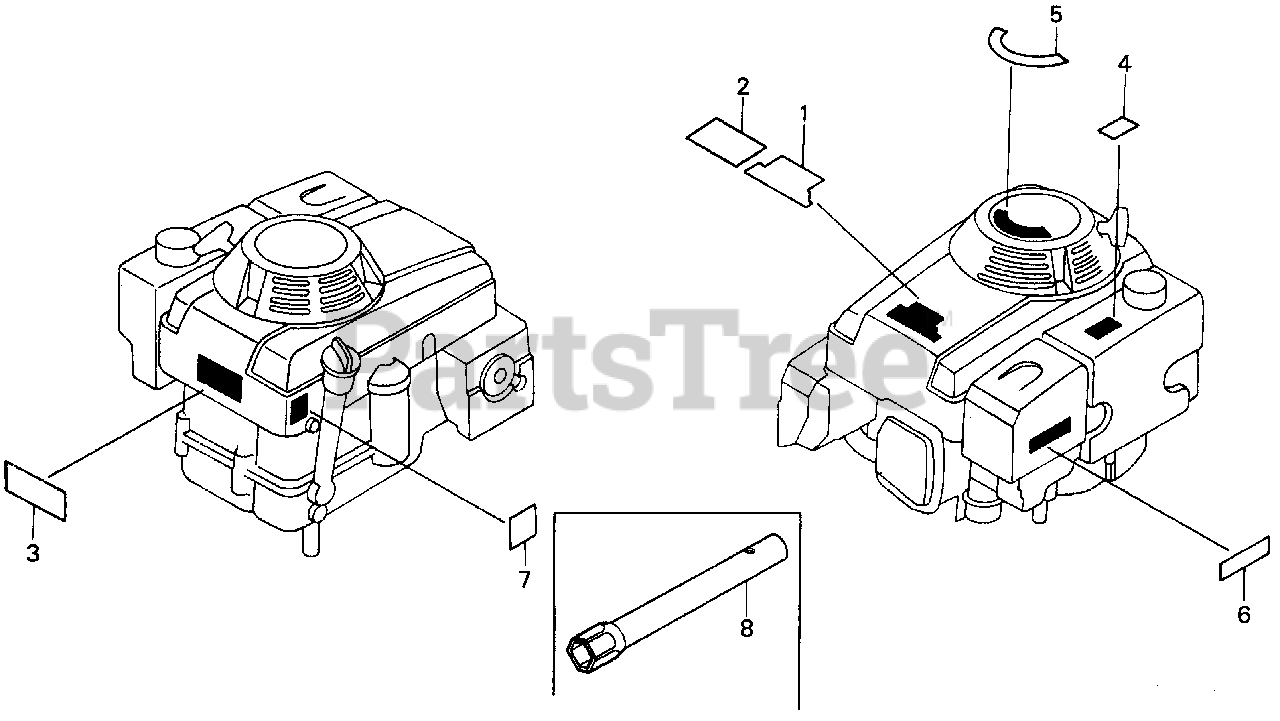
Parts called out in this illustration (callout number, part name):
2	MARK, TOP COVER (OIL ALERT)
3	MARK, CAUTION
3	LABEL, EMBLEM (ENGLISH/FRENCH/GERMAN)
5	MARK, EASY START (ENGLISH)
6	MARK, AIR CLEANER CAUTION
7	MARK, OIL CAUTION
8	WRENCH, BOX (P21)
